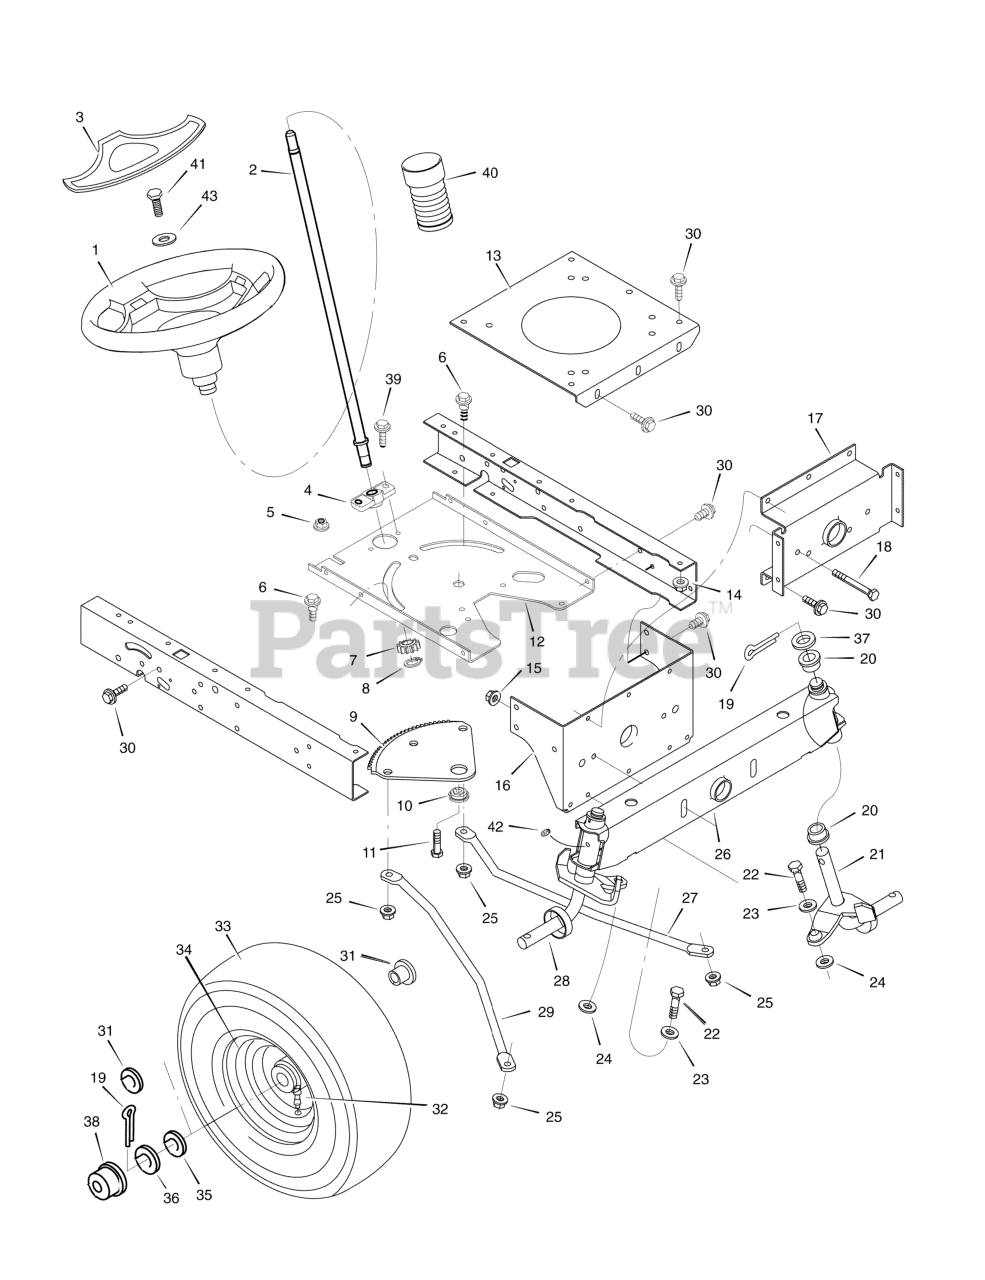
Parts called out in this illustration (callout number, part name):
1	Wheel, Steering 4 Spoke
2	Post, Steering
3	Cover, Steering Wheel
4	Bearing
5	Nut, Flange **
6	Bolt, Shoulder
7	GEAR, Pinion **
8	Ring, Snap **
9	Gear, Sector
10	Bearing
11	CAPSCREW, Hex Head, 5/16-18 x 1
12	Plate, Steering
13	Plate, Engine
14	Nut, Flange
15	Nut, Flange
16	Bracket, Hanger
17	Axle, Hanger
19	Pin, Cotter
20	Bearing
21	Spindle Assembly, Left
22	Bolt
24	Washer
25	Nut, Flange
26	Axle Assembly
27	Drag Link, Left
28	Spindle Assembly, Right
29	Drag Link, Right
31	Bearing, Wheel
32	Stem, Valve
34	Wheel and Tire Assembly
38	Hub Cap
40	Bellows
41	Screw, Hex
42	Fitting, Lube
43	Washer
